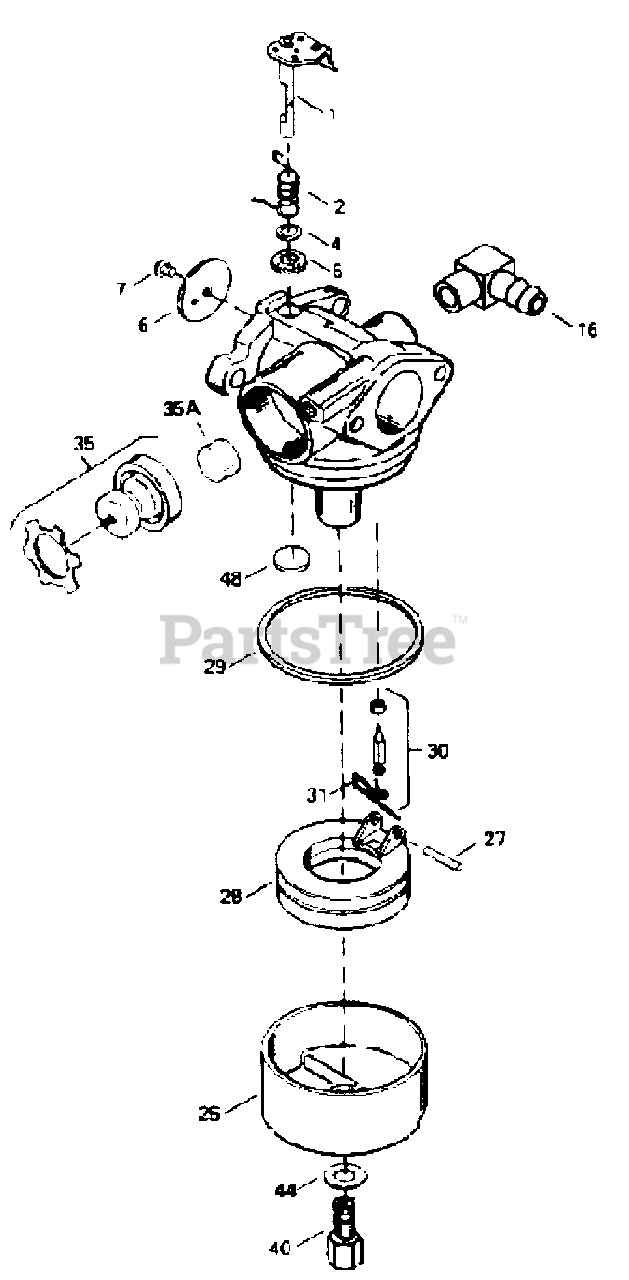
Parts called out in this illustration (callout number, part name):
1	Throttle Shaft & Lever Assembly
2	Throttle Return Spring
4	Dust Seal Washer
5	Dust Seal (Throttle)
6	Throttle Shutter
7	Shutter Screw
16	Fuel Fitting
25	Float Bowl
27	Float Shaft
29	Float Bow "O" Ring
30	Inlet Needle, Seat, & Clip (Incl. 31)
31	Spring Clip
35	Primer Bulb/Retainer Ring
35A	Primer Bulb Filter
40	High Speed Bowl Nut
44	Bowl Nut Washer
48	Welch Plug, Atmospheric Vent
